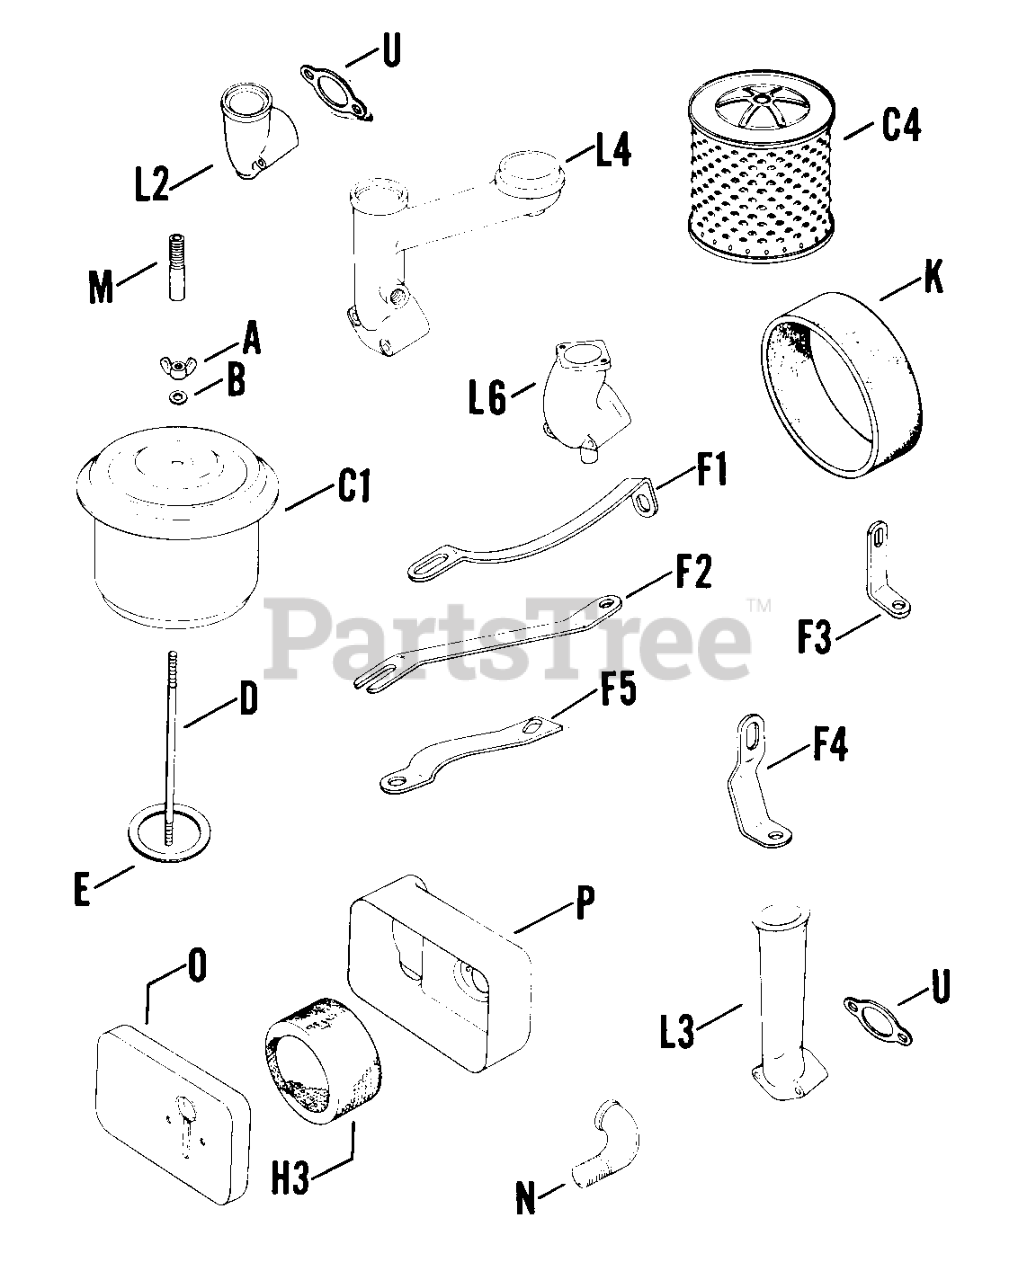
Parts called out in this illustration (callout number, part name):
A	NUT, WING 1/4-20 USE 25 100 15-S
K	PRE-CLEANER
K	PRE-CLEANER USE 234869-S
U	GASKET - USE 41 041 11
